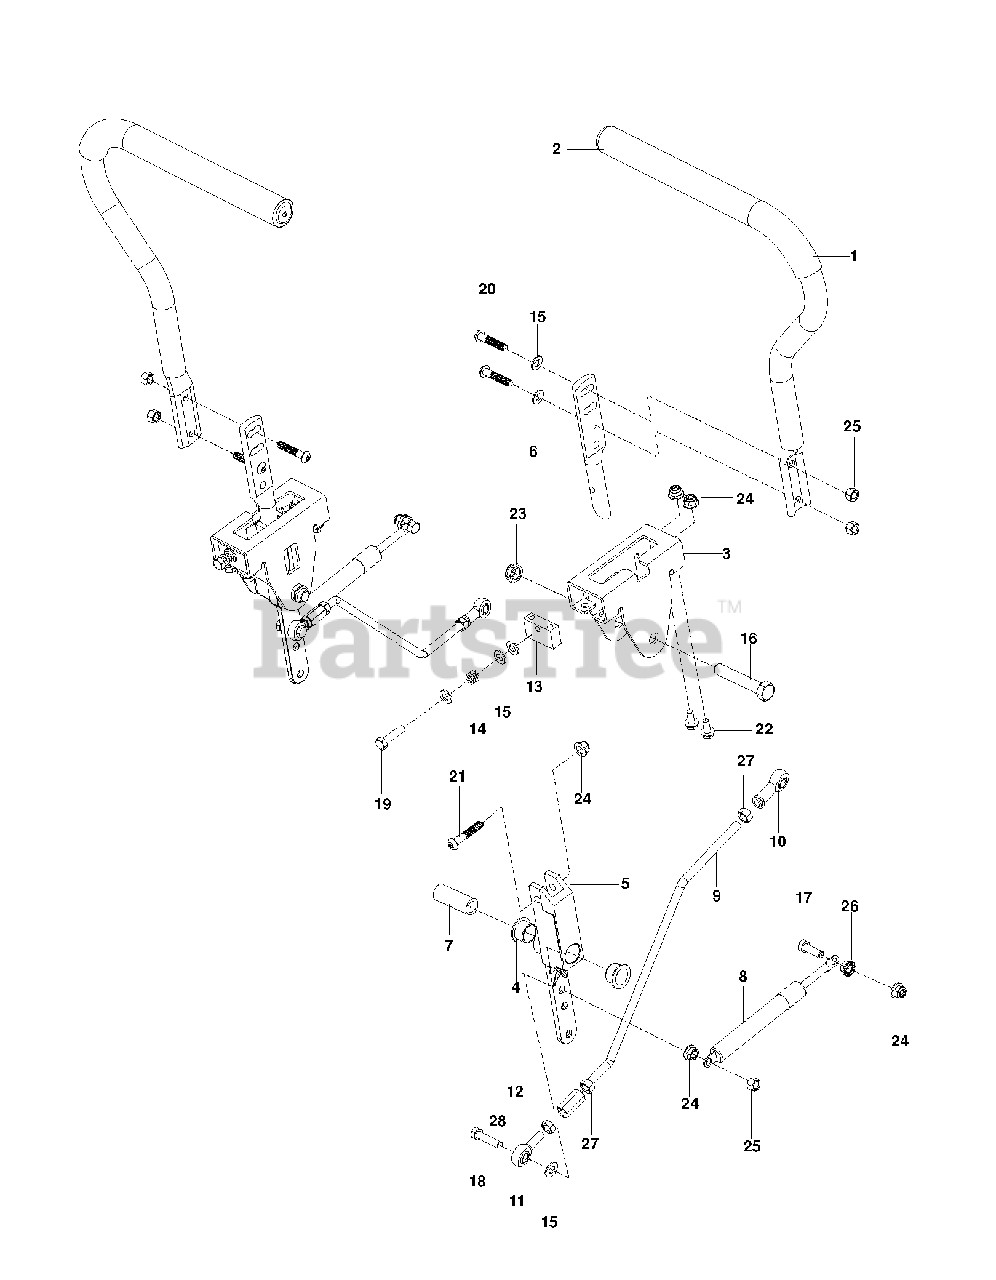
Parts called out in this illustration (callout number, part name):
2	GRIP, DRIVE LEVER
3	BRACKET, CONTROL
4	BEARING, FLANGE
5	LEVER CONTROL PIVOT
7	SPACER, PIVOT CONTROL
8	DAMPENER
10	RH ROD END
11	ROD END LH
12	ROD END COUPLER
13	BLOCK, TRACKING
15	FLAT WASHER 5/16 SAE
16	HCS 1/2C X 2 3/4
17	HCS 5/16C X 1
18	HCS 5/16-18X1-3/4 TPBLT
19	CAPSCREW 5/16 X 1/1/2 HEX HEAD
20	SCREW 5/16-18 X 1 BTN-HD
22	HHFS 5/16-18 X 3/4
23	NUT 1/2-13 HEX JM NYL
24	5/16-18 NYLOC FLANGE NUT
25	NUT 5/16 NYLOC
26	NUT 5/16C WHIZ
27	NUT 5/16F
28	NUT 5/16F LEFTHAND
